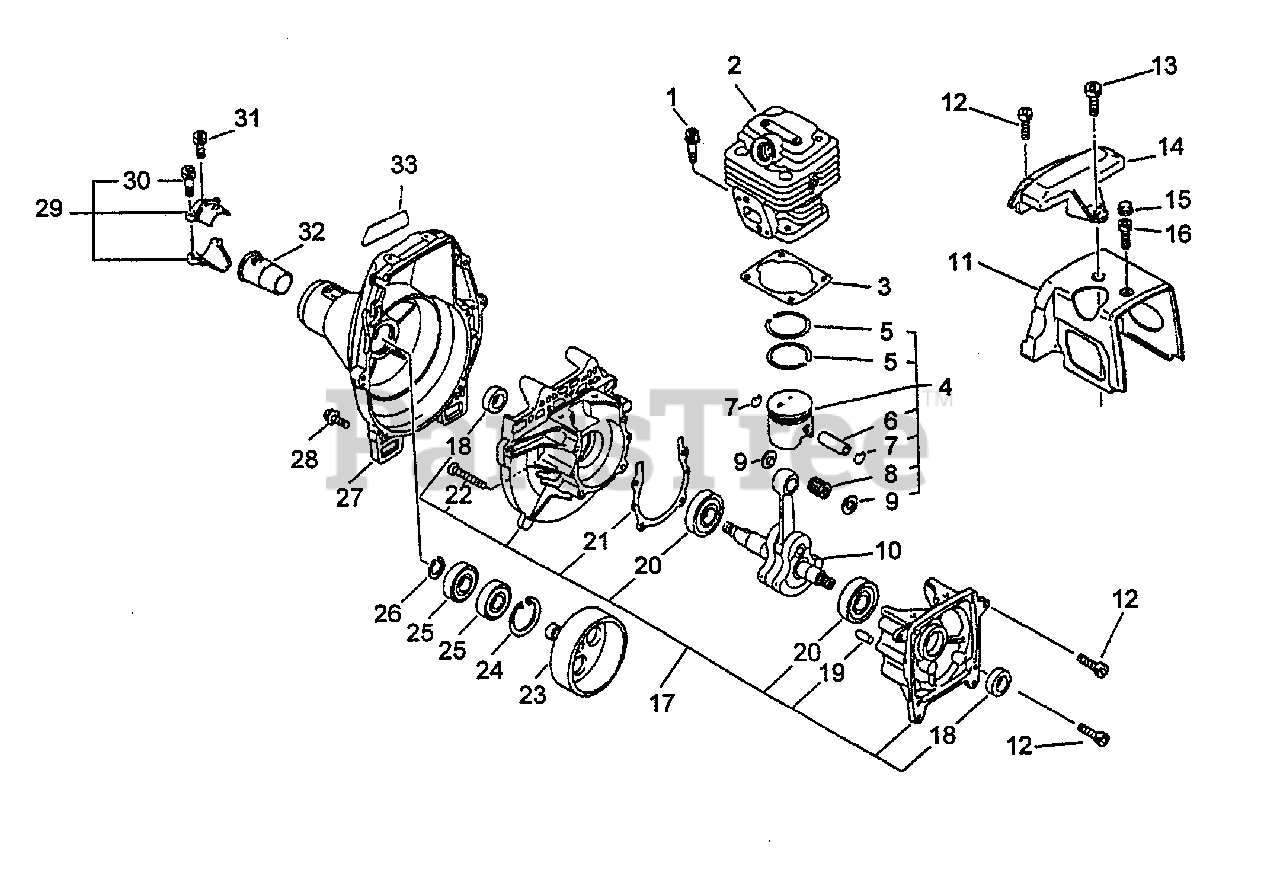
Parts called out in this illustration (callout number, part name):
1	SCREW - 5X20
2	CYLINDER
3	GASKET, CYLINDER
4	PISTON KIT
5	RING, PISTON
6	PIN, PISTON
7	RING, RETAINING
8	BEARING, NEEDLE
9	SPACER, PISTON
10	CRANKSHAFT ASSY
11	COVER, ENGINE
12	SCREW - 4X14
13	SCREW - 5X16
14	GUARD - TOP
16	SCREW - 5X12
17	CRANKCASE KIT
18	SEAL, OIL
19	PIN - LOCATING
20	BEARING, BALL - 6201
21	GASKET, CRANKCASE
22	SCREW - 5X30
23	DRUM, CLUTCH
24	RING, RETAINING - 28
25	BEARING, BALL - 6001
26	RING, RETAINING - 12
27	CASE, FAN
28	SCREW - 5X20
29	HOLDER KIT
30	SCREW - 5X25
31	SCREW - 5X12
33	LABEL - MODEL SRM-3400
